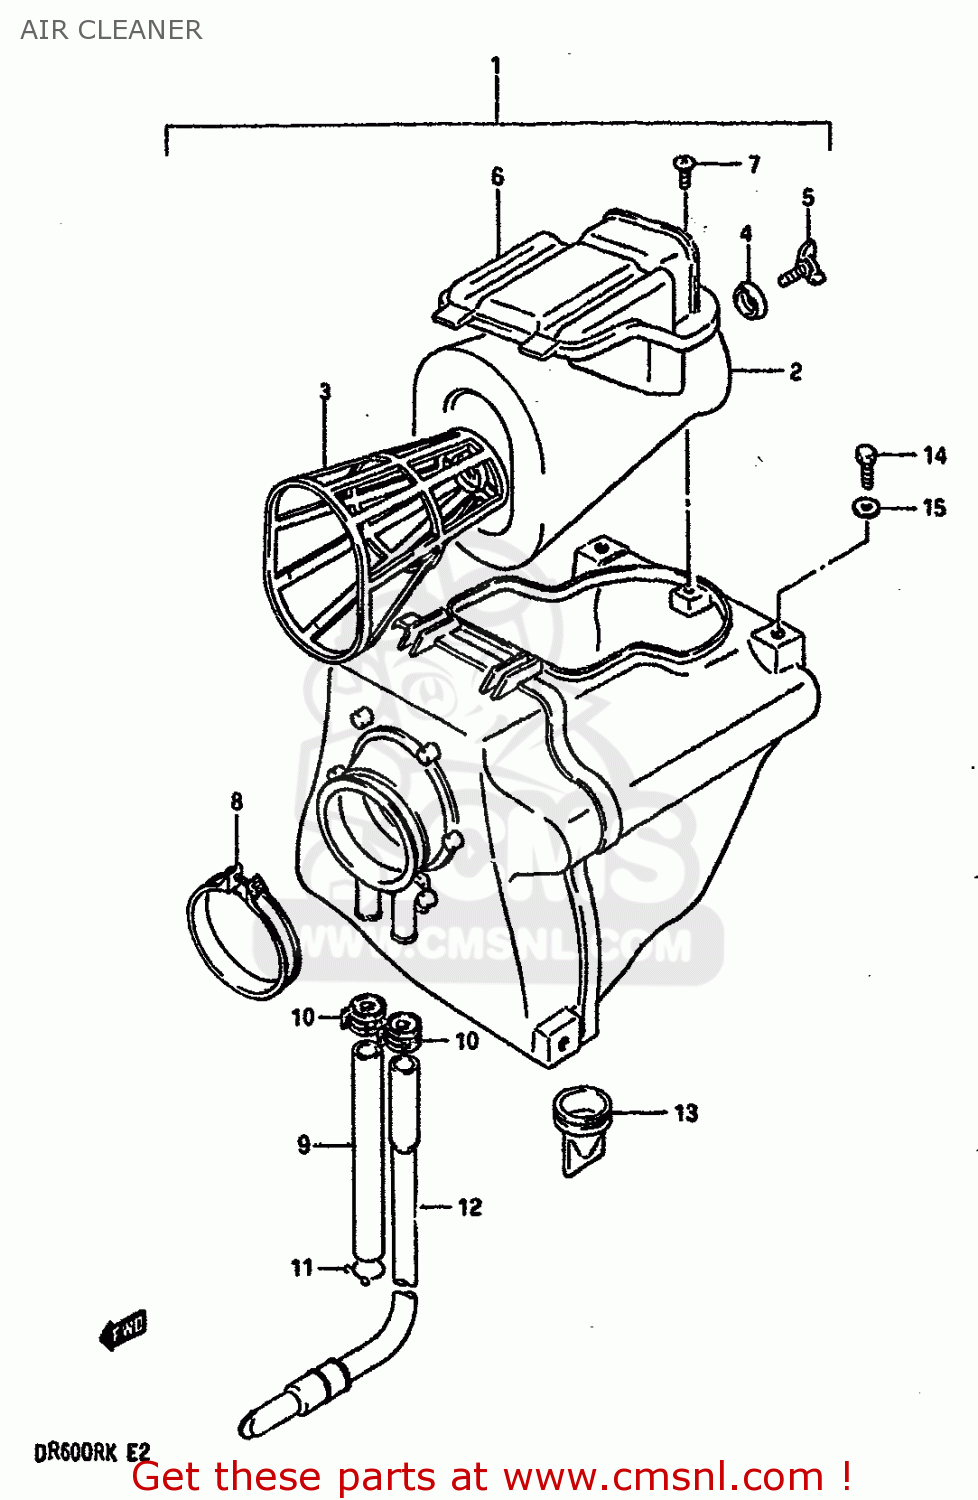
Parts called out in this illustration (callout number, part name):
1	CLEANER ASSY,AIR
2	FILTER,AIR CLEANER
3	HOLDER
4	WASHER,FILTER HOLDER
5	BOLT,AIR CLEANER
6	CAP,AIR CLEANER
7	SCREW
8	CLAMP
9	TUBE,BREATHER
10	CLIP
11	CLIP
12	DRAIN TUBE
13	HOSE,AIR CLEANER DRAIN
14	BOLT(6X14)
15	WASHER
